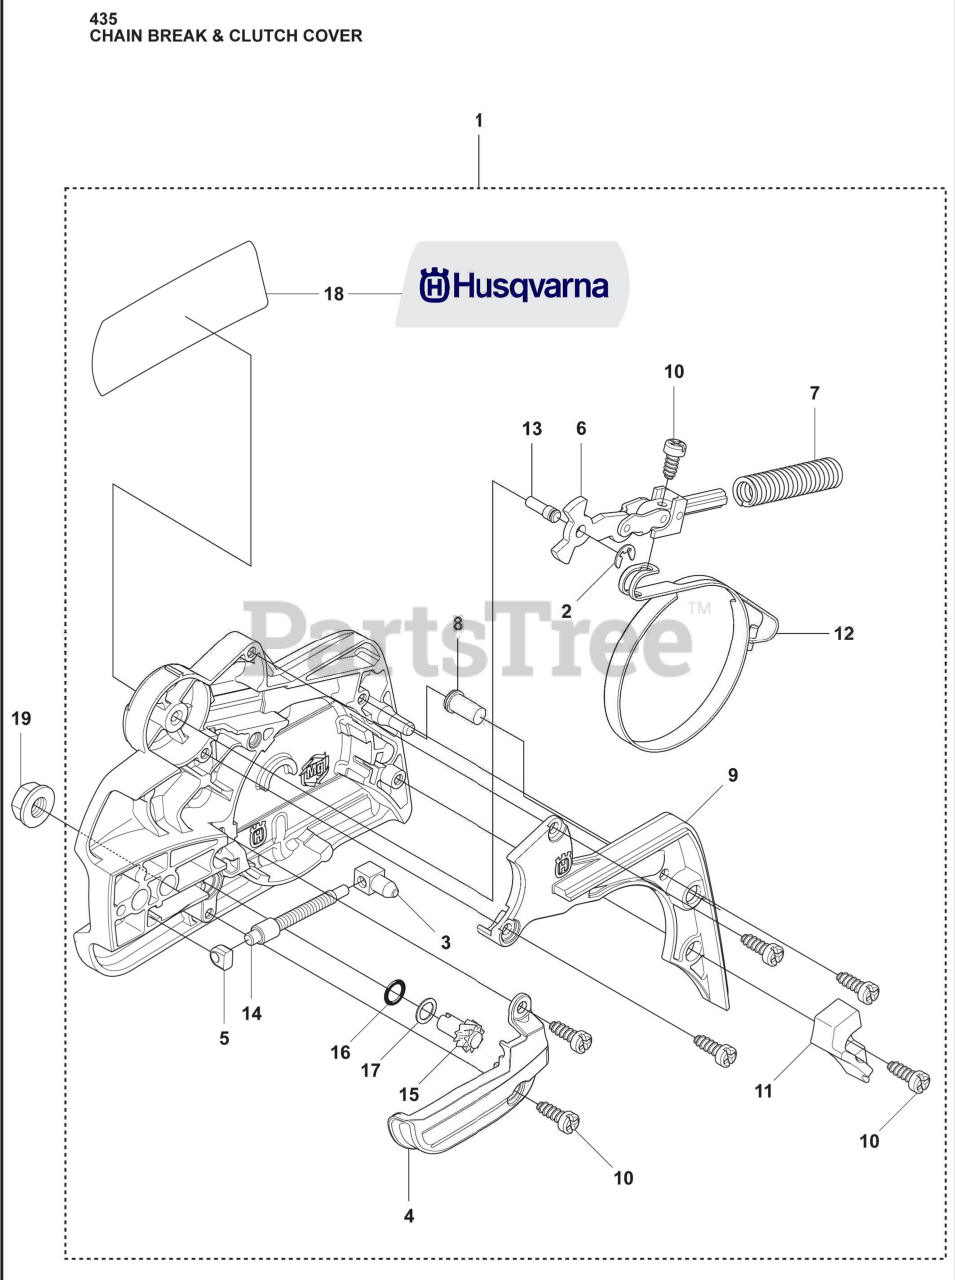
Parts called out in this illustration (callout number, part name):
1	Clutch Cover Assembly
2	Bar Retainer
3	Pawl
4	Chain Guide
5	Sleeve
6	Joint
7	Brake Spring
8	Sleeve
9	Cover
10	Screw
11	Wear Protection
12	Brake Band Assembly
13	Pin
14	Worm Screw
15	Worm Wheel
16	O-Ring
17	Washer
18	Label, 400 Series
19	Flange Hex Nut, M8
